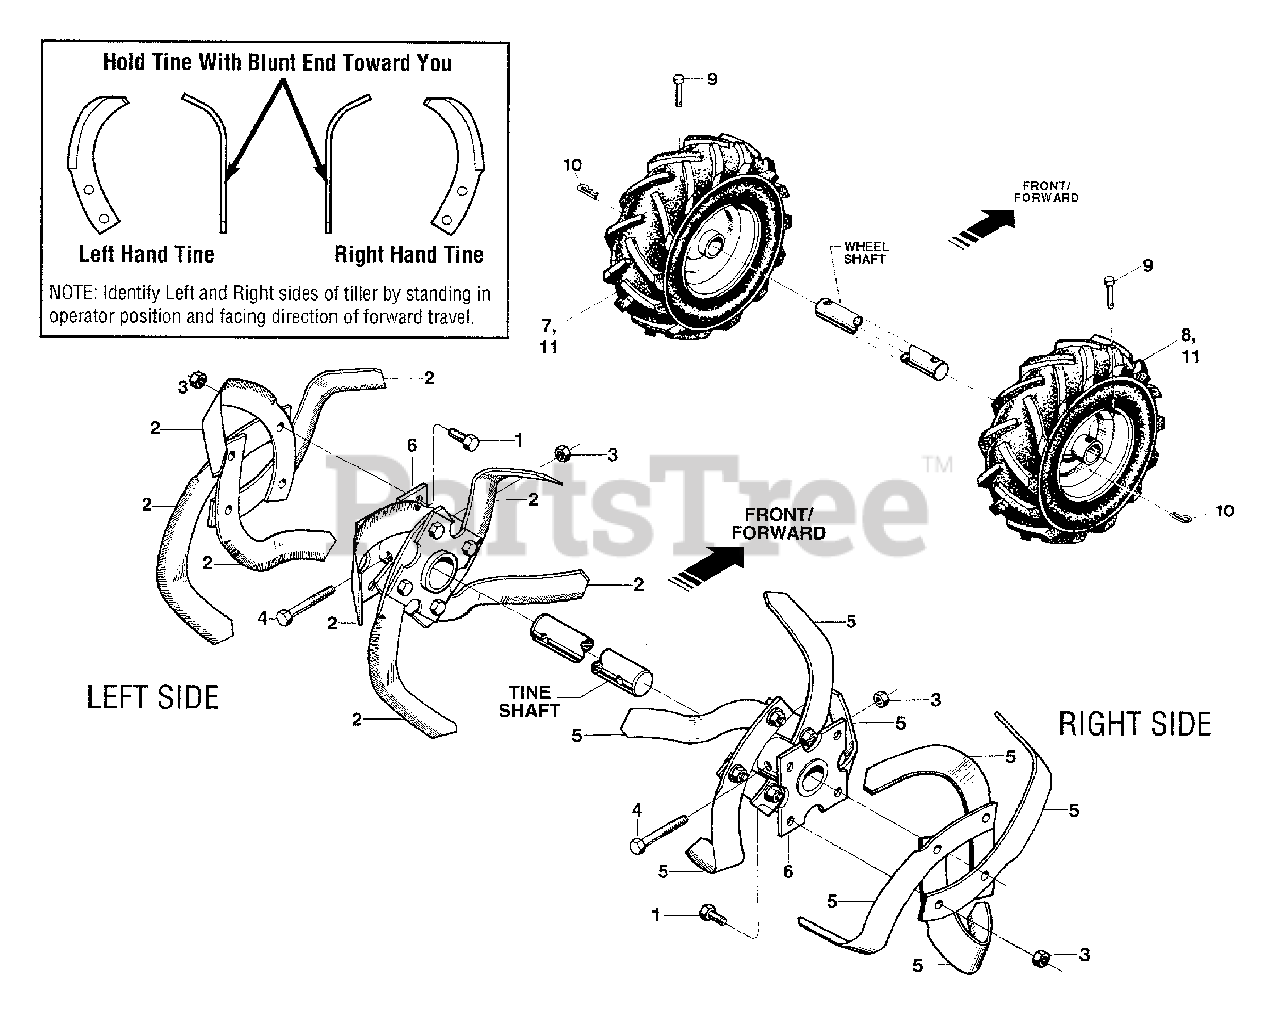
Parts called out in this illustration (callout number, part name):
1	Hex Screw, 3/8-16 x 1, Grade 5
2	Bolo Tine - Right Hand.
3	Hex Locknut, 3/8-16
4	Hex Screw, 3/8-16 x 1-3/4
5	Bolo Tine - Left Hand.
6	Tine Holder
7	Wheel & Tire Assy-Left Side
8	Wheel & Tire Assy-Right Side
9	Clevis Pin, .312" x 1-3/4"
10	Hair Pin Cotter
11	Wheel & Tire Assy
